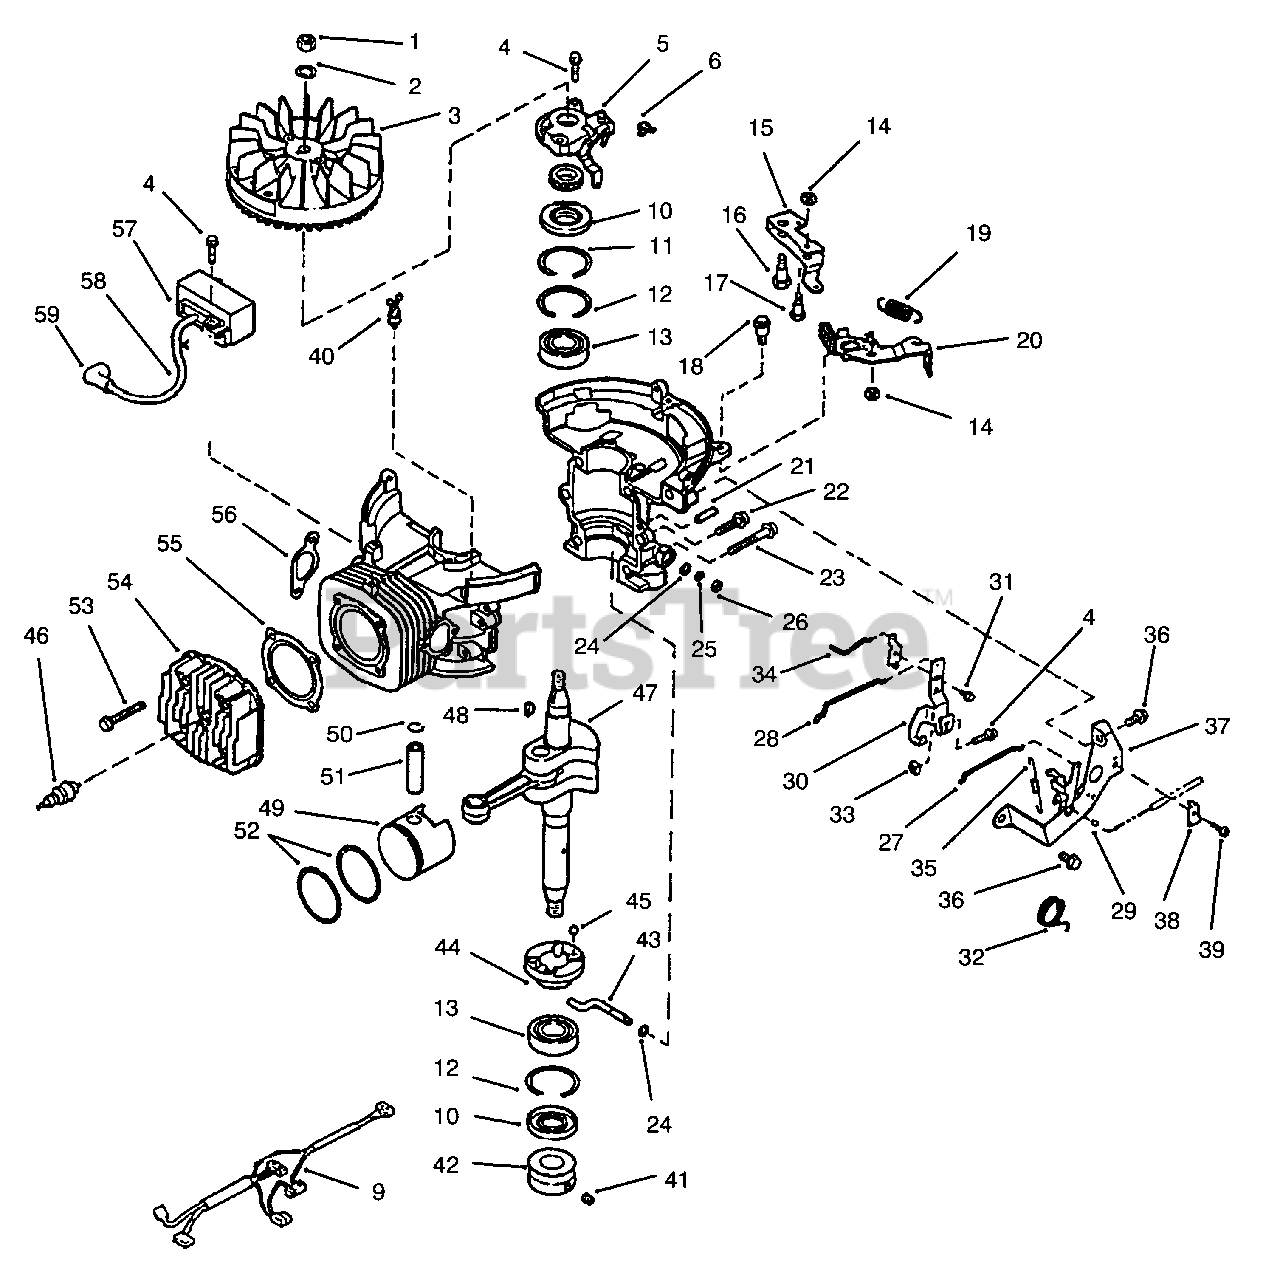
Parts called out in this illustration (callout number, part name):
1	Nut-Flywheel
2	Lockwasher
3	Flywheel
5	Oil Pump Kit w/Oil Lines (Incl. Ref. No. 6)
6	Clamp-Oil Line
9	Wire Harness
10	Oil Seal-Crankshaft
11	Ring-Retaining
12	Ring-Retaining
13	Bearing-Crankshaft
15	Brake Actuator
16	Shoulder Bolt
17	Shoulder Bolt
18	Shoulder Bolt
19	Brake Spring
20	Brake & Switch
21	Pin-Taper
24	Washer-Governor Shaft
25	Ring-Retain.-Gov. Shaft
26	Seal-Oil,Governor Shaft
27	Rod-Choke
28	Rod-Throttle
29	Retainer-Throttle Wire
30	Kit-Gov. & Oil Pump Lever(Incl. Ref. No. 31)
32	Spring-Torsion
34	Rod-Oil Pump Control
35	Spring-Governor
37	Assy.-Governor Bracket(Incl. Ref. No. 32)
38	Clamp-Throttle Cable
40	Wire Tie
41	Screw-Set,Engine Pulley
42	Pulley-Engine
43	Shaft-Governor
44	Ramp-Governor
45	Ball-Governor
46	Spark Plug
47	Crankshaft & Conn. Rod
49	Assy-Piston & Ring (Std) (Incl. Ref. No. 50-52)
50	Ring-Retaining
51	Pin-Wrist
52	Ring Set (Standard)
52	Ring Set (0.020" Oversize)
53	Screw-Cyl. Head to Block
54	Head-Cylinder
55	Gasket-Head
56	Gasket-Exhaust
57	Module-C.D. Ignition(Incl. Ref. No. 58-59)
58	High Tension Lead & Cover(Incl. Ref. No. 59)
59	Assy.-Cover & Terminal
